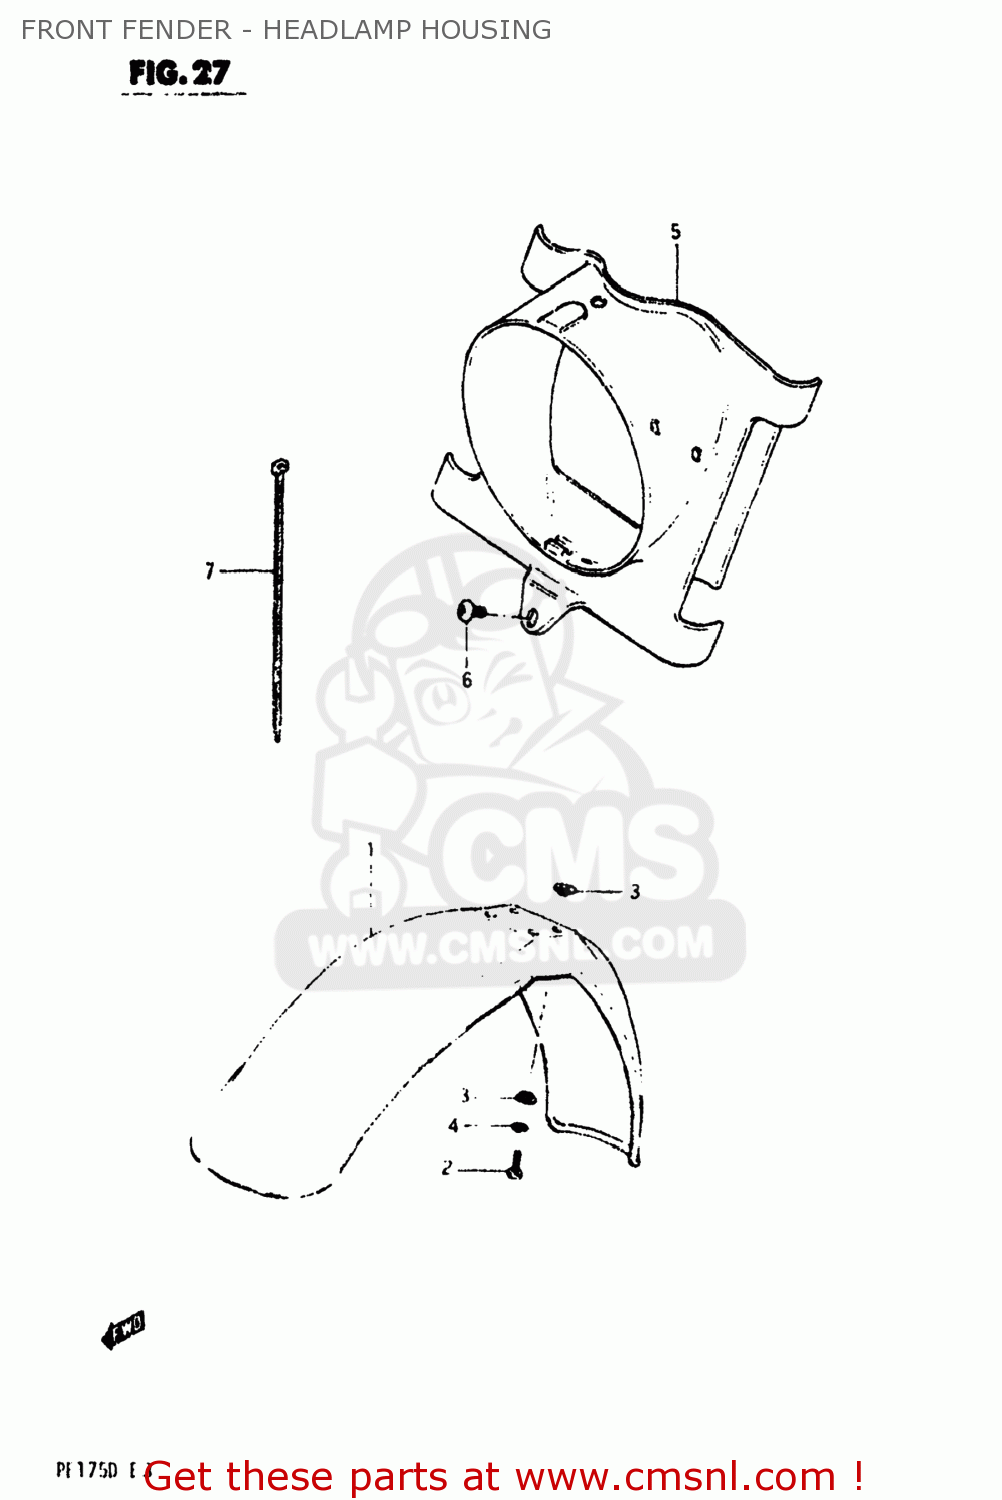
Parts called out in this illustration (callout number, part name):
1	FENDER,FRONT
2	BOLT, UPPER
3	SPACER
4	LOCK WASHER
5	HOUSING,HEADLAMP
6	SCREW
7	CLAMP
